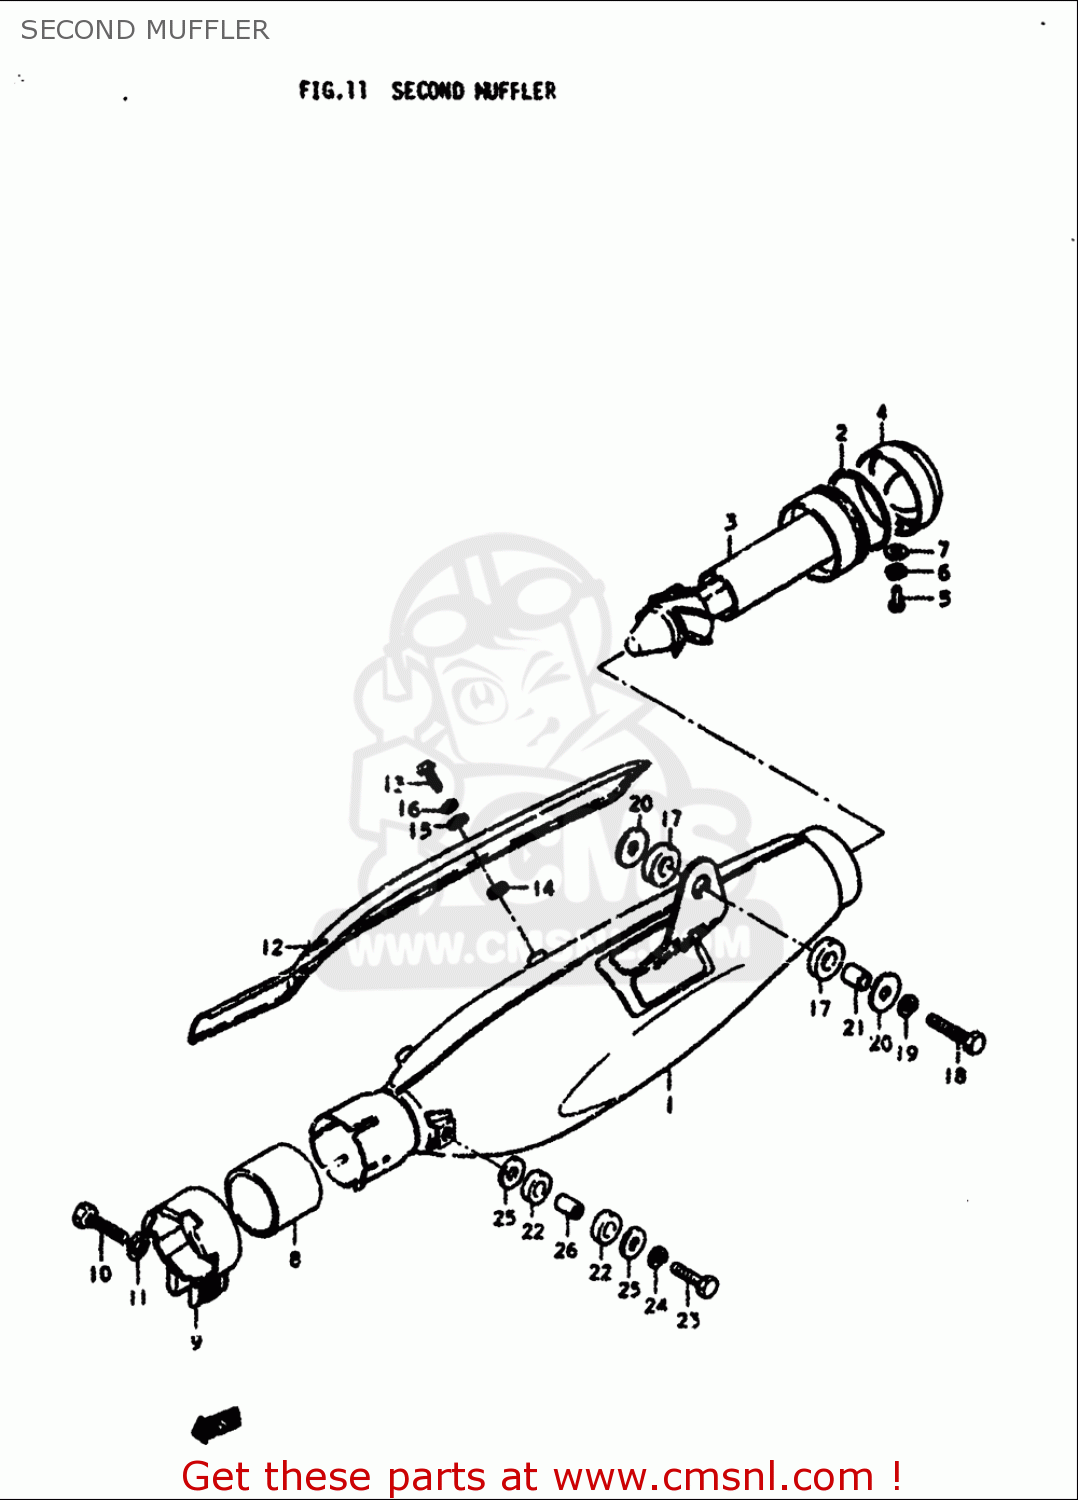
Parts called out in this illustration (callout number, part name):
1	MUFFLER ASSEMBLY,SECOND
5	SCREW(6X8)
6	WASHER,LOCK
7	WASHER
8	CONNECTOR,MUFFLER
9	CLAMP
10	BOLT
11	WASHER
13	SCREW
14	GASKET(6.2X12X1.5) (NAS)
15	WASHER
16	WASHER,LOCK
17	CUSHION
18	BOLT
19	WASHER,LOCK
20	WASHER(8.5X28X1.6)
21	SPACER (8.6X13.8X13)
22	CUSHION
23	BOLT
24	WASHER,LOCK
25	WASHER(8.5X26X1.6)
26	SPACER(8.5X14X8)
